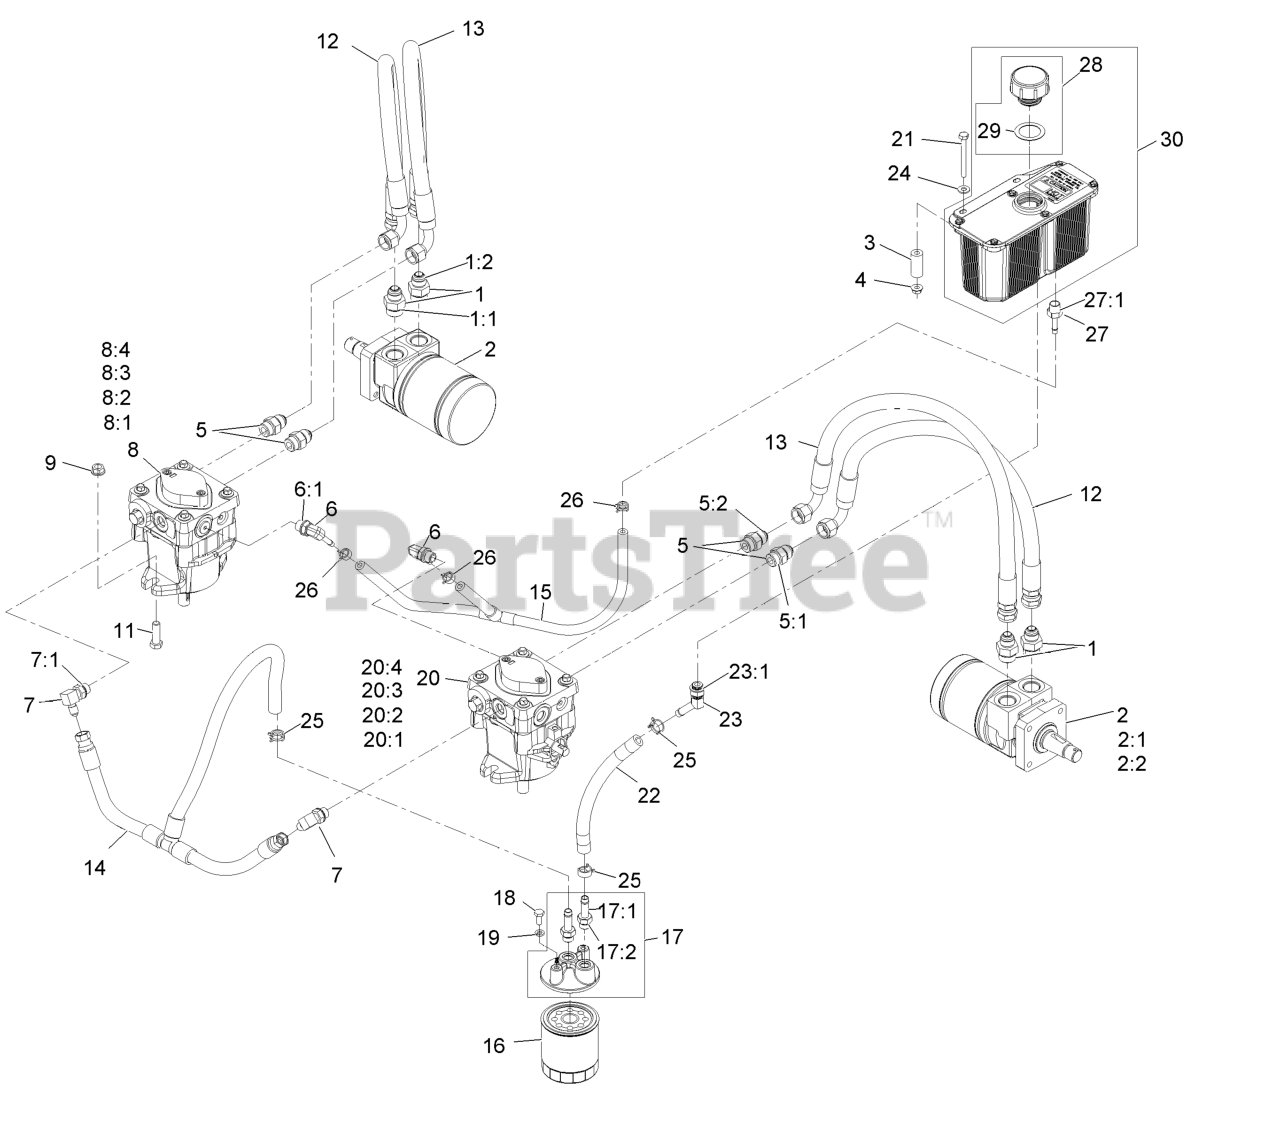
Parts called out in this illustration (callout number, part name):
1	FITTING-STRAIGHT
2	HYD MOTOR ASM
2:1	BEARING AND SEAL KIT
2:2	SEAL KIT
5	FITTING-STRAIGHT
6	ELBOW-90 DEG
7	FITTING-ELBOW, 90 DEG
8	LH HYD PUMP ASM
8:1	INPUT SHAFT KIT
8:2	BEARING-THRUST
8:3	CYLINDER BLOCK KIT
8:4	SEAL OVERHAUL KIT
9	NUT-FLANGE
11	SCREW-HH
13	HOSE-PRESSURE, HIGH
14	CHARGE HOSE ASM
15	CASE DRAIN HOSE ASM
16	FILTER-25 MICRON, BI-DIRE
16	ELEMENT-FILTER, WINTER
17	FILTER HEAD ASM
17:1	ADAPTER-STRAIGHT
18	SCREW-HH
19	WASHER-LOCK
20	RH HYD PUMP ASM
20:1	INPUT SHAFT KIT
20:2	BEARING-THRUST
20:3	CYLINDER BLOCK KIT
20:4	SEAL OVERHAUL KIT
21	SCREW-HH
22	HOSE-CHARGE
23	FITTING-BARBED, 45 DEG
24	WASHER-FLAT
25	CLAMP-HOSE
26	CLAMP-HOSE
27	ADAPTER-STRAIGHT
28	KIT,HYD RES CAP W/GASKET
29	GASKET-CAP
30	HYD RESERVOIR ASM
